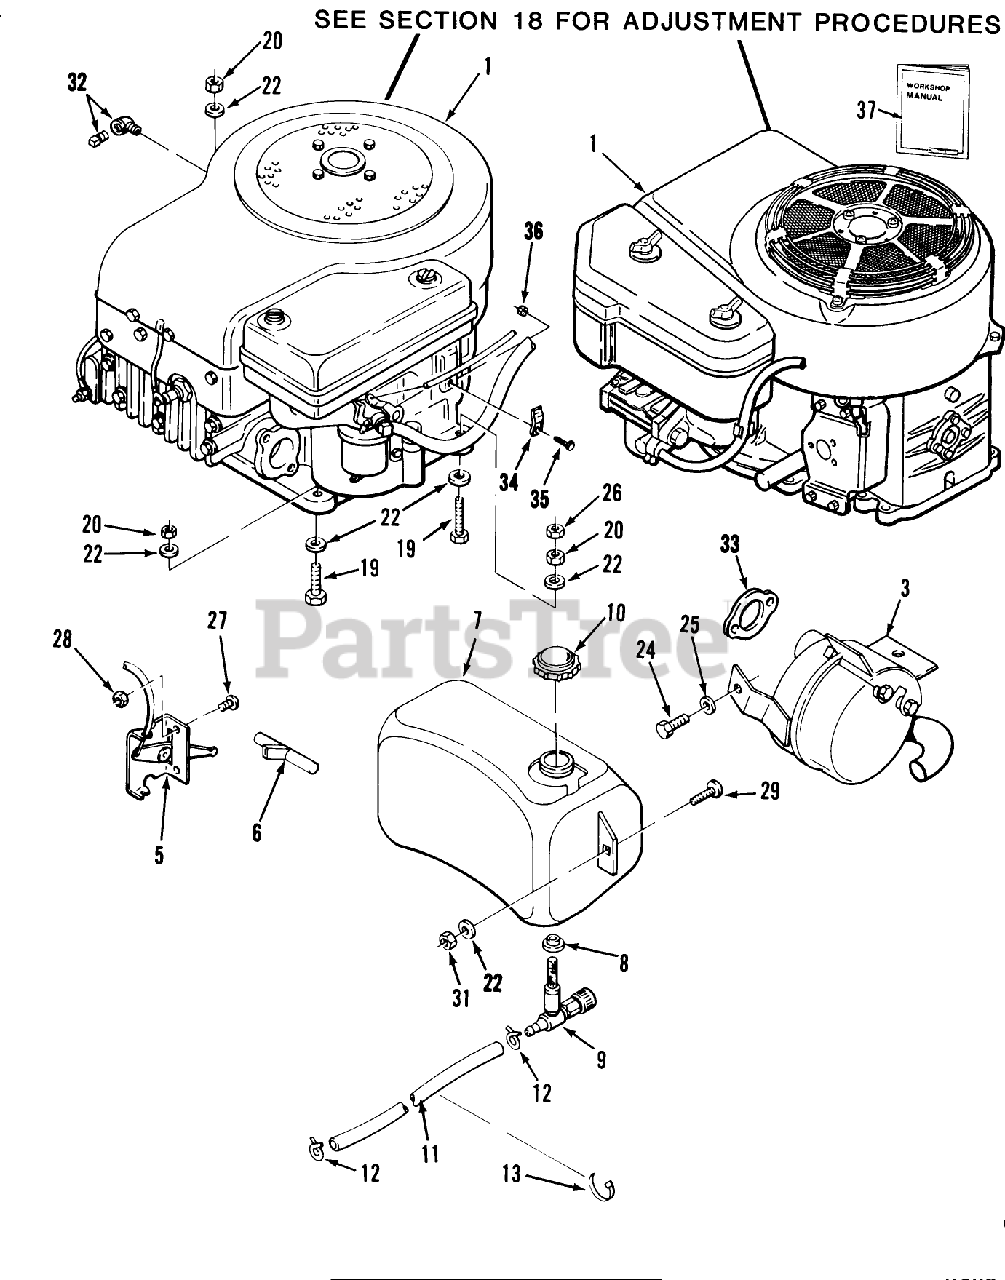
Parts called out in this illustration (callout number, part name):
1	Engine-8HP-BS Model 191707, Type 2175-01 208-4 Only
1	Engine-11HP-BS Model 253707, Type 0222-01 211-5 Only
10	CAP GAS
22	WASHER 5/16 SAE
32	STREET ELBOW 45DEGRE
36	Throttle Screw Nut
37	Kawasaki FB460V Workshop Manual
